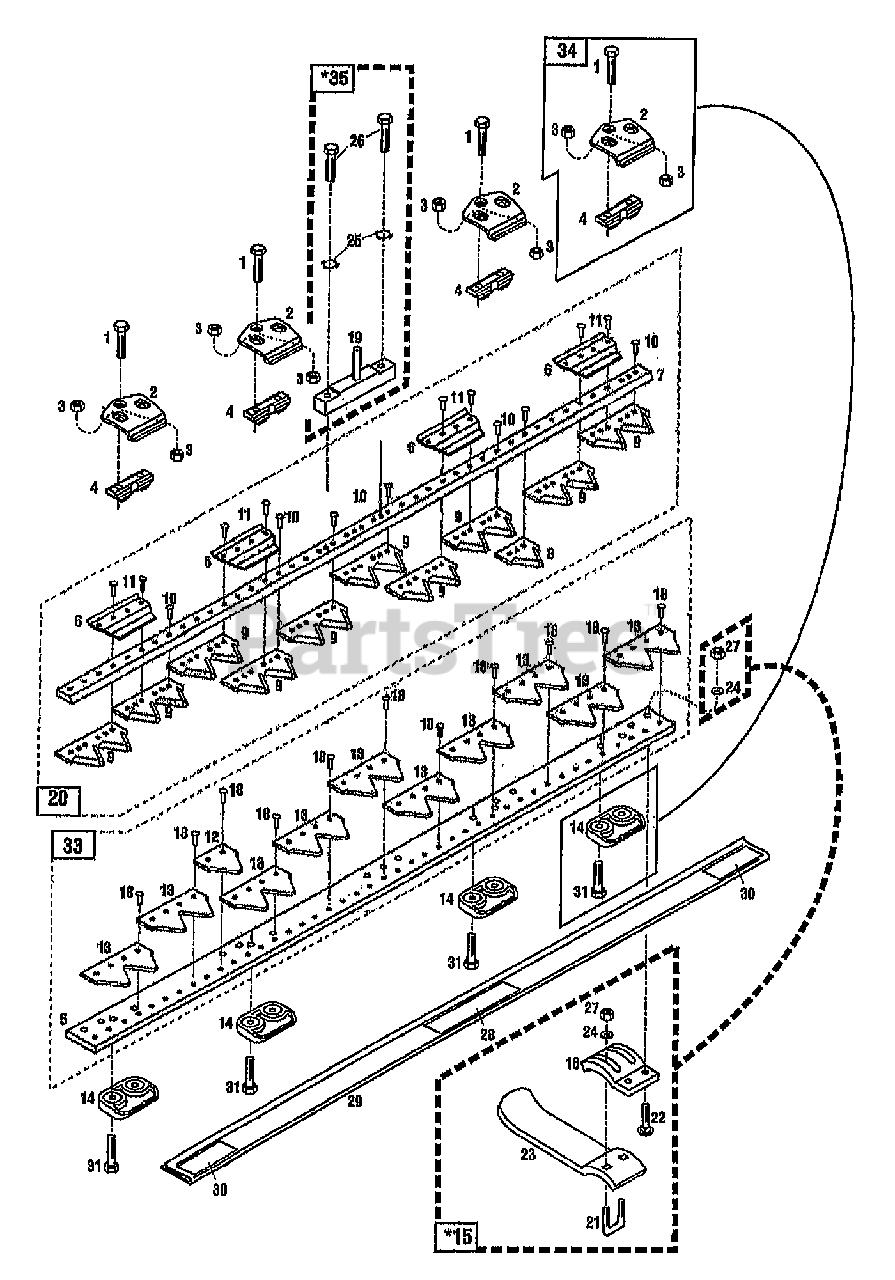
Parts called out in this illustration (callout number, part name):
1	SCR-HHC M8-1.25X30
2	CLIP-HOLD DOWN
3	NUT-H/LK M8
4	GUIDE-KNIFE
5	KNIFE-BACK BAR 34"
5	BAR-BACK 38"
5	BAR-BACK 42"
6	PLATE-WEAR
7	BAR-KNIFE 34"
7	BAR-KNIFE 38"
7	BAR-KNIFE 42"
8	KNIFE SECTION SINGLE
9	KNIFE SECTION DOUBLE 34"
9	KNIFE SECTION DOUBLE 38"
9	KNIFE SECTION DOUBLE 42"
10	KIT-RIVET 5X17 12 PKG
11	KIT-RIVET 5X20 12 PKG
12	PLATE-LEDGER SINGLE
13	PLATE-LEDGER DOUBLE
15	ASSM-SKID 2PC SET W/HDW (INCL. 16,21-24&27)
16	SHOE-SPUR HOLDER PNT
17	WASHER-FLAT M8
18	KIT-RIVET/SEC 6X20=12 PER
19	KIT-KNIFE HEAD & PITMAN (04 & LOWER)
19	HEAD-KNIFE (05 & HIGHER)
20	ASSM-34" BLADE T/B SICKLEBAR (INCL. 6-11)
20	ASSM-38" KNIFE T/B SICKLEBAR (INCL. 6-11)
20	ASSM-42" KNIFE T/B SICKLEBAR (INCL. 6-11)
21	BOLT-U 5/16"-18
22	SCR-CARR 5/16-18X1.0 G2 ZP
23	SHOE-PNT
24	WASHER-FLAT 5/16 SAE
25	WASHER-LK .312 INT TOOTH (04 & LOWER)
25	WASHER .703X.359X.065 (HARDENED)(05 & UP)
26	BOLT-M8X25
27	NUT-H/LK 5/16-18 (04 & LOWER)
27	NUT-H/LK 5/16-18 NYLOCK (05 & UP)
28	DECAL-DANGER
29	COVER-BLADE
29	GUARD-BLADE 38"
29	GUARD-BLADE 42"
30	DECAL-ESM
31	SCR-HH M8X45
32	KIT-BLADE MAINT T/B SKLBR
33	ASSM-BACK BAR 34"
33	ASSM-BACK BAR 38"
33	ASSM-BACK BAR 42"
34	KIT-HOLD DOWN (INCL. 1-4,14,31)
35	KIT-KNIFE HEAD & PITMAN (04 & LOWER)
35	KIT-KNIFE HEAD/PITMAN (05 & UP)
36	LOCTITE-242 (.5 ML TUBE)
